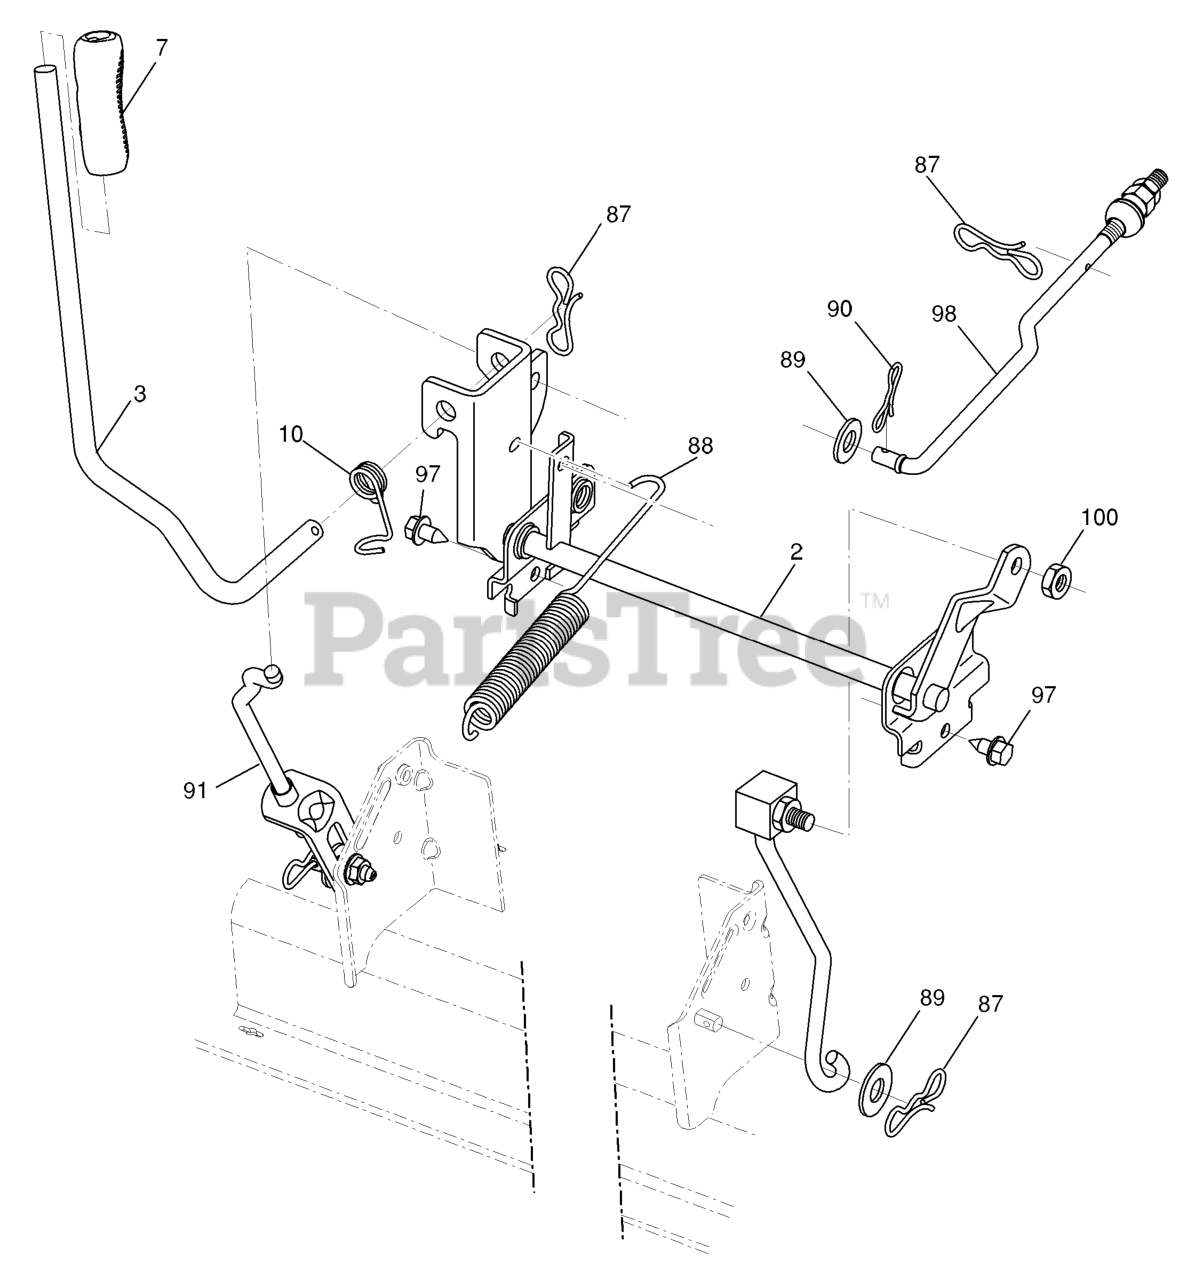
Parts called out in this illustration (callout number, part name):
2	SHAFT.ASM.LIFT.CROSS.H
3	LEVER.LIFT.HANDLE.LT
7	GRIP.HANDLE.LIFT.PVC.BLACK
10	SPRING.TORSION.LIFT.HANDLE
87	PIN.COTTER.7/16.BOW TI.
88	SPRING.LIFT.ASSIST.LT
89	WASHER.CLEAR.ZINC
90	PIN.COTTER.5/16.BOW TI
91	LINK.ASM.LIFT.REAR
97	SCREW 3/8-16X3/4
98	LINK.ASM.SUSP.FRONT.MW
100	LOCKNUT
